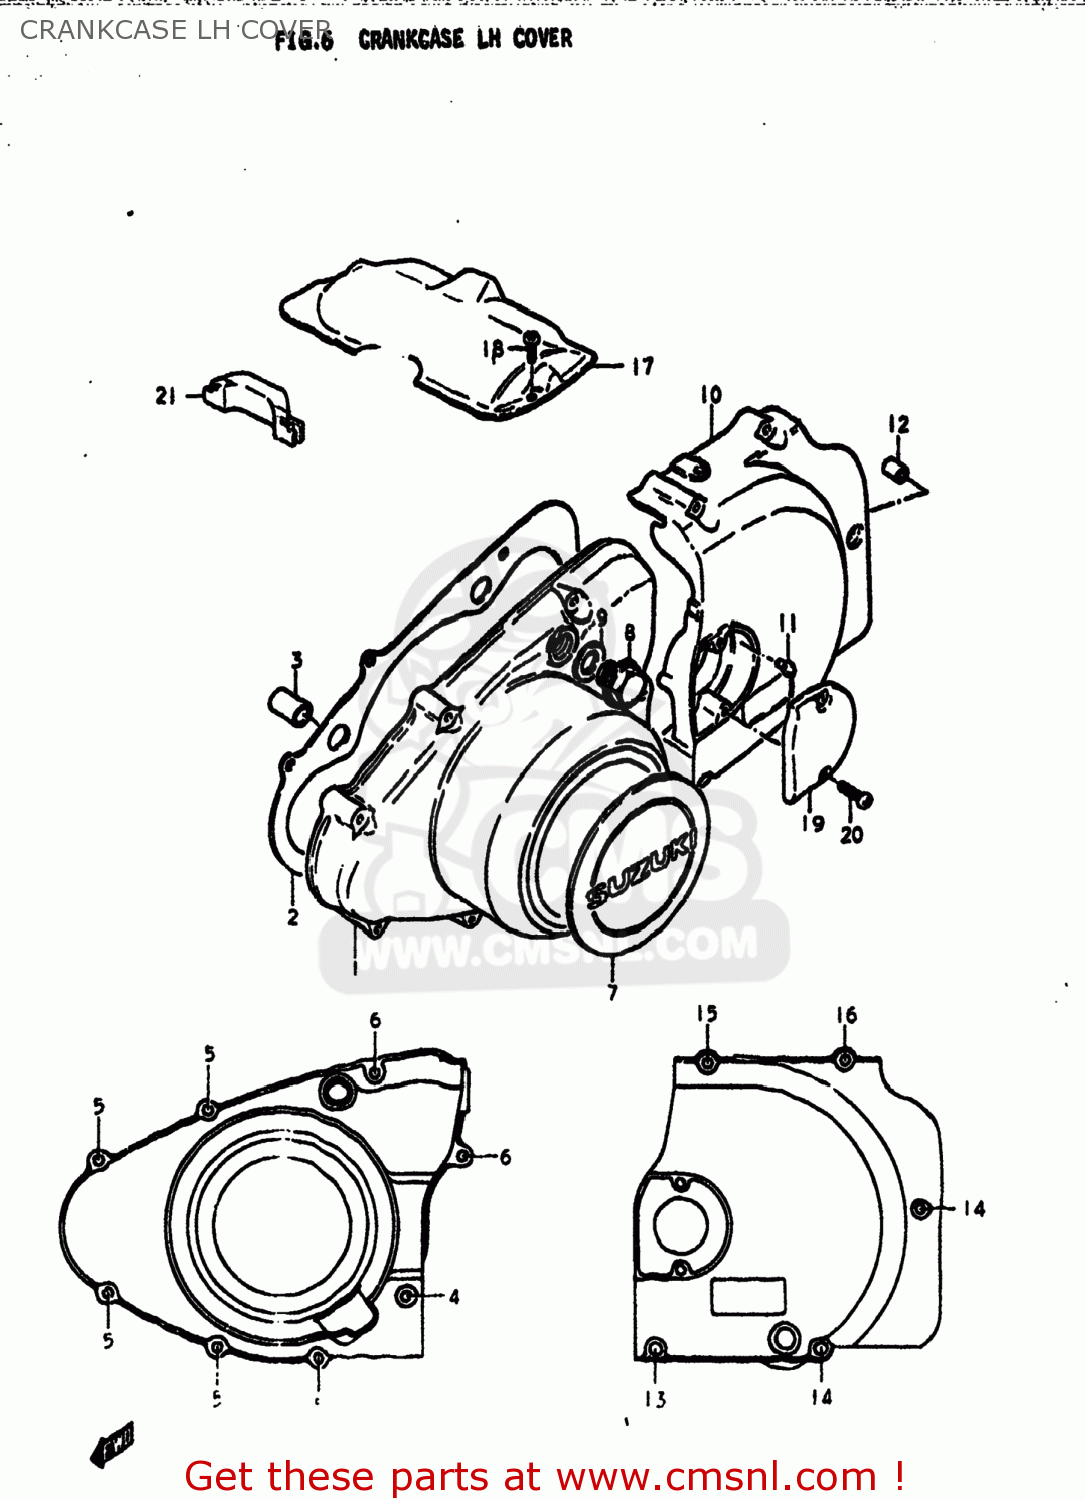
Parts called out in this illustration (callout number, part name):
1	COVER
2	GASKET,MAGNETO COVER (MCA)
3	PIN
4	SCREW
5	SCREW (6X35)
6	SCREW
7	EMBLEM
8	PLUG (14X12)
9	GASKET(14X19.2X2) (NAS)
10	COVER,ENGINE SPROCKET
11	NIPPLE
12	PIN
13	SCREW 6X65
14	SCREW 6X60
15	SCREW
16	SCREW
17	COVER,STARTER MOTOR
18	SCREW
19	CAP,CLUTCH RELEASE ADJUST
20	SCREW
21	GROMMET,STARTING MOTOR
